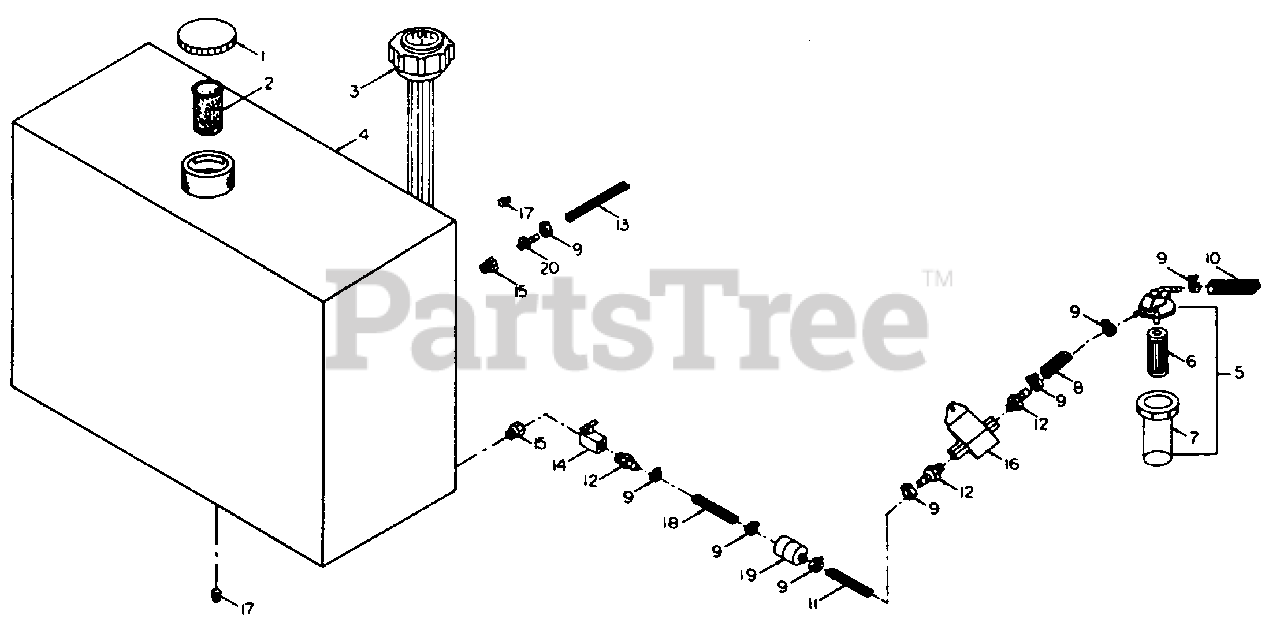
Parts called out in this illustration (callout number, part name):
2	Fuel Tank Screen
3	Fuel Tank Cap w/Gauge
4	Fuel Tank
5	Fuel Filter Ass'y., Diesel Only
6	Fuel Filter Element
7	Fuel Filter Bowl
8	Fuel Line, 5/16" x 3-1/2"
9	Hose Clamp, 3/8" 10
10	Fuel Line, 5/16" x 30"
11	Fuel Line, 5/16" x 6"
12	Male Pipe, 1/8", Barb Adpt., 5/16
13	Fuel Return Line, 3/16", Diesel
14	Brass Shutoff Valve, 1/8"
15	Male Pipe, 3/8", Female Pipe Adpt., 1/8"
16	Electric Fuel Pump, Diesel
17	Pipe Plug, 3/8", Diesel
18	Fuel Line, 5/16" x 2"
19	Inline Fuel Filter, 5/16"
20	Male Pipe, 1/8", Barb Adpt., 3/16", Diesel
